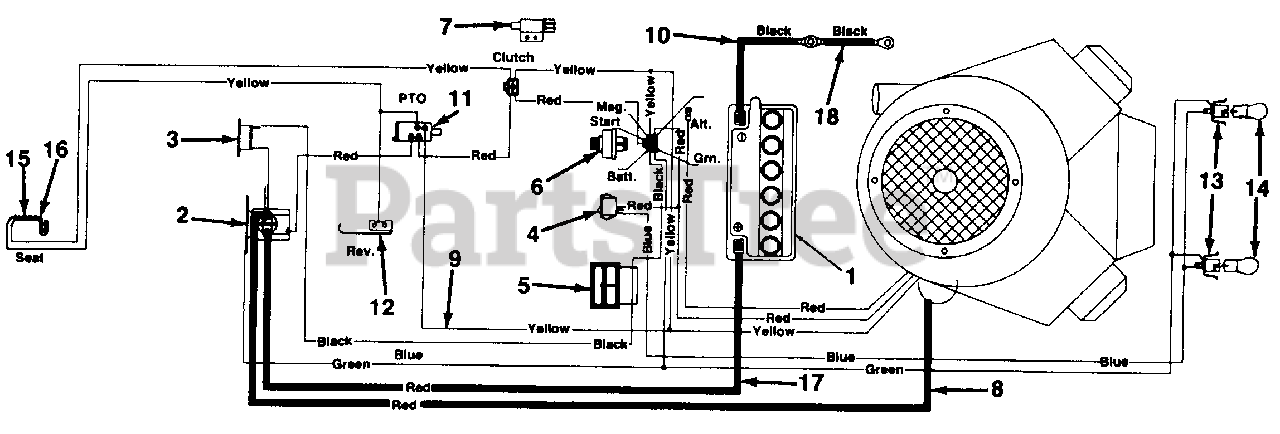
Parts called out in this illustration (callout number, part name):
1	Battery-1 2V
2	Solenoid
3	Circuit Breaker
4	Light Switch
5	Ammeter
6	Ignition Switch
7	Safety Switch
8	Electric Wife-30.0" Lg.
9	Wire Harness
10	Ground Wire-11.5" Lg.
11	Safety Switch
12	Safety Switch
13	Headlight Socket
14	Headlight Bulb
15	Safety Switch
16	Safety Switch
17	Electric Wire-27" Lg.
18	Ground Wire-7.5" Lg.
